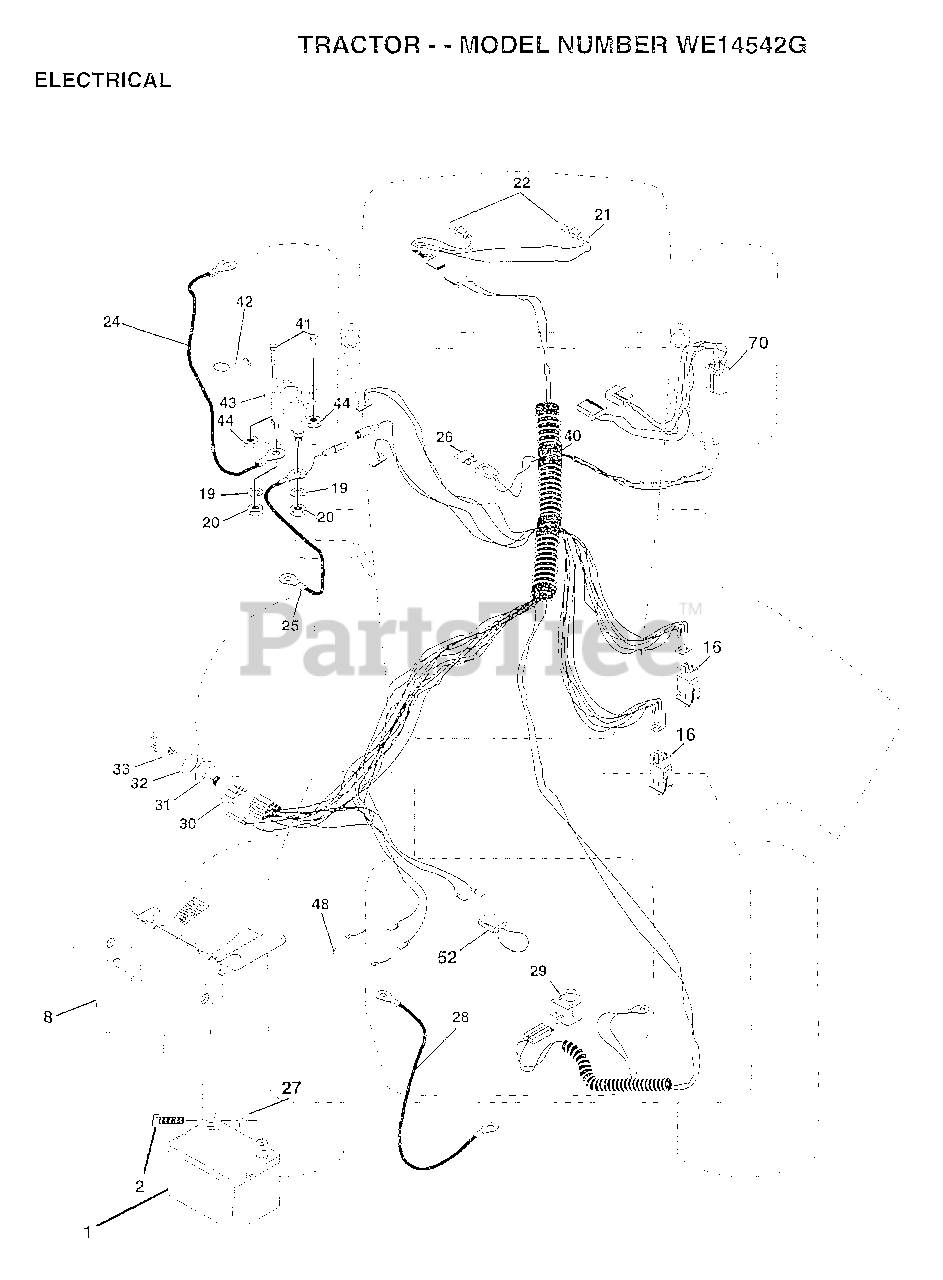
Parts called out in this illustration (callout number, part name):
2	BOLT LT
8	"CASE,BATTERY.MECH"
16	SWITCH INTERLOCK
20	NUT
21	"HARNESS,LIGHT SOC"
22	HEADLAMP BULB
24	"CABLE T, BATTERY"
25	CABLE.BTRY.6GA.RD
26	FUSE HYT
27	NUT
28	CABLE T
29	SWITCH SEAT
30	SWITCH IGN 4POS
31	NUT IGNITION
32	COVER KEY SWITCH
33	KEY
40	HARNESS-IGNITION
41	BOLT HXHD FIN
44	NUT HXKEP 1/4X20
48	ADAPTER AMMETER
52	PROTECTION LOOP
70	HARNESS.ENG.DUAL
